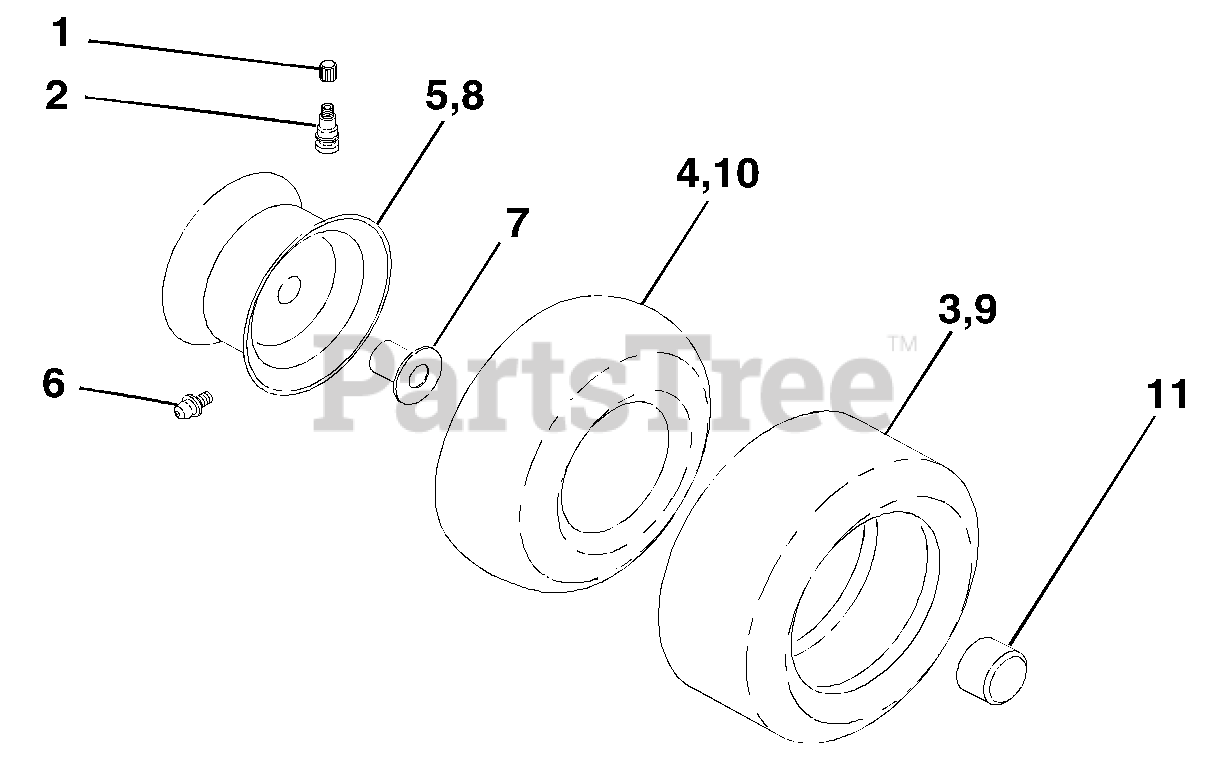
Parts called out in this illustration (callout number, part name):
1	Cap Valve Tire
2	Stem Valve
3	Tire F Ts 15 X 6 0 - 6 Service
4	Tube Front (Service Item Only)
5	Rim Asm 6" front Service
6	Fitting Grease (Front Wheel Only)
7	Bearing Flange (Front Wheel Only)
8	Rim Asm 8" rear Service
9	Tire R Ts 20x10-8 C Service
10	Tube Rear (Service Item Only)
11	Cap Axle 1 50 X 1 00
